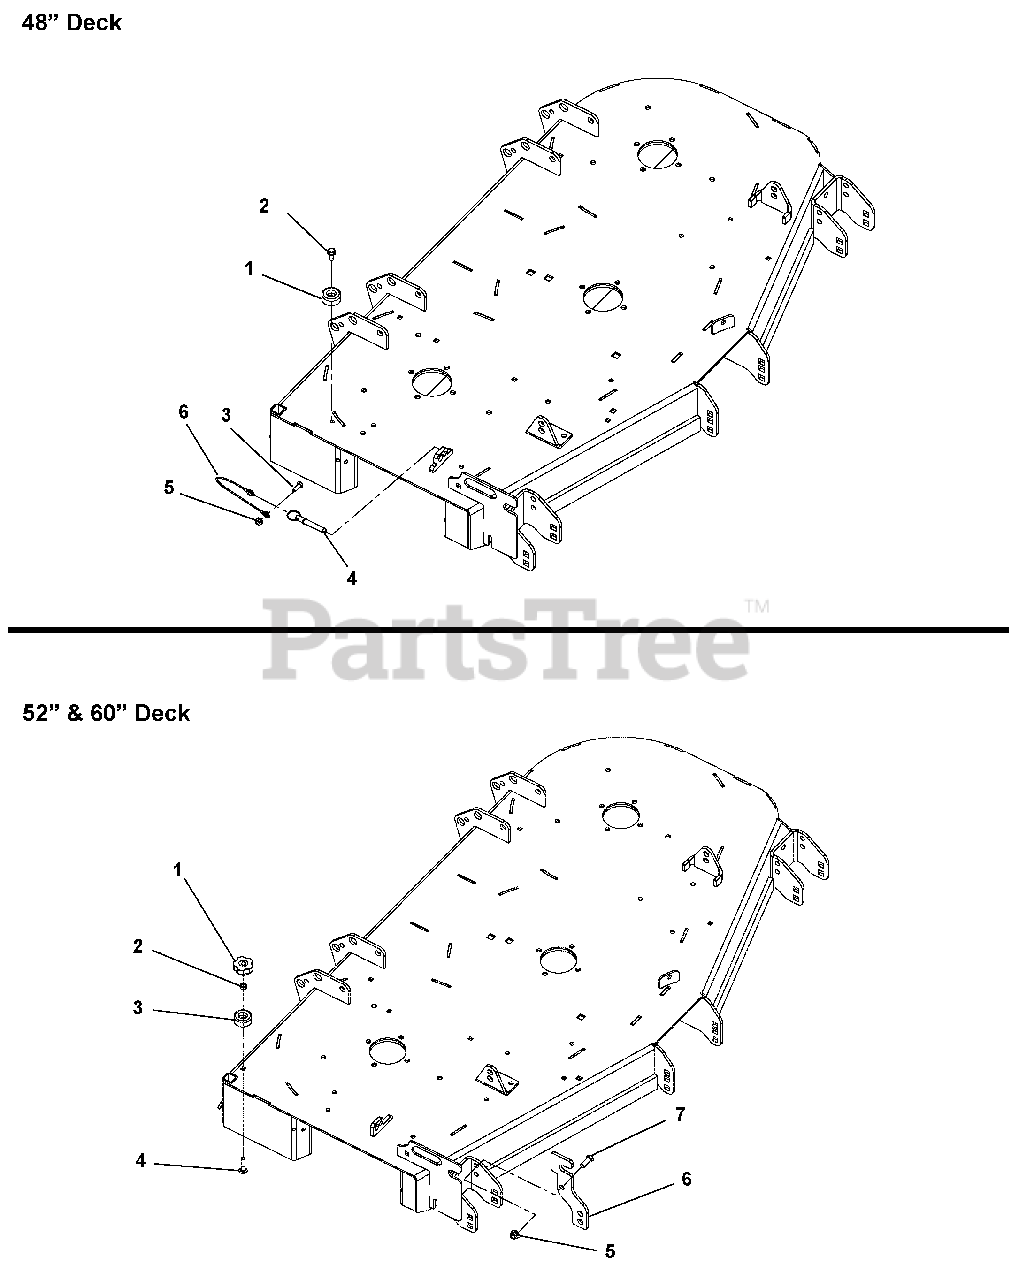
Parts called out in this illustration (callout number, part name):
1	Bumper, Recessed 1.50 x .63 w/.31 Thru Hole
2	Screw, Tapping .31-18 x .75 Hex Washer Head Thread Rolling
3	Bolt, Hex .25-20 x .75 Grade 5
4	Pin, Spring Ball .375OD x 1.50
5	Nut, Locking-Top-Flange .25-20
6	Cable, 6.0 Lanyard, Nylon
